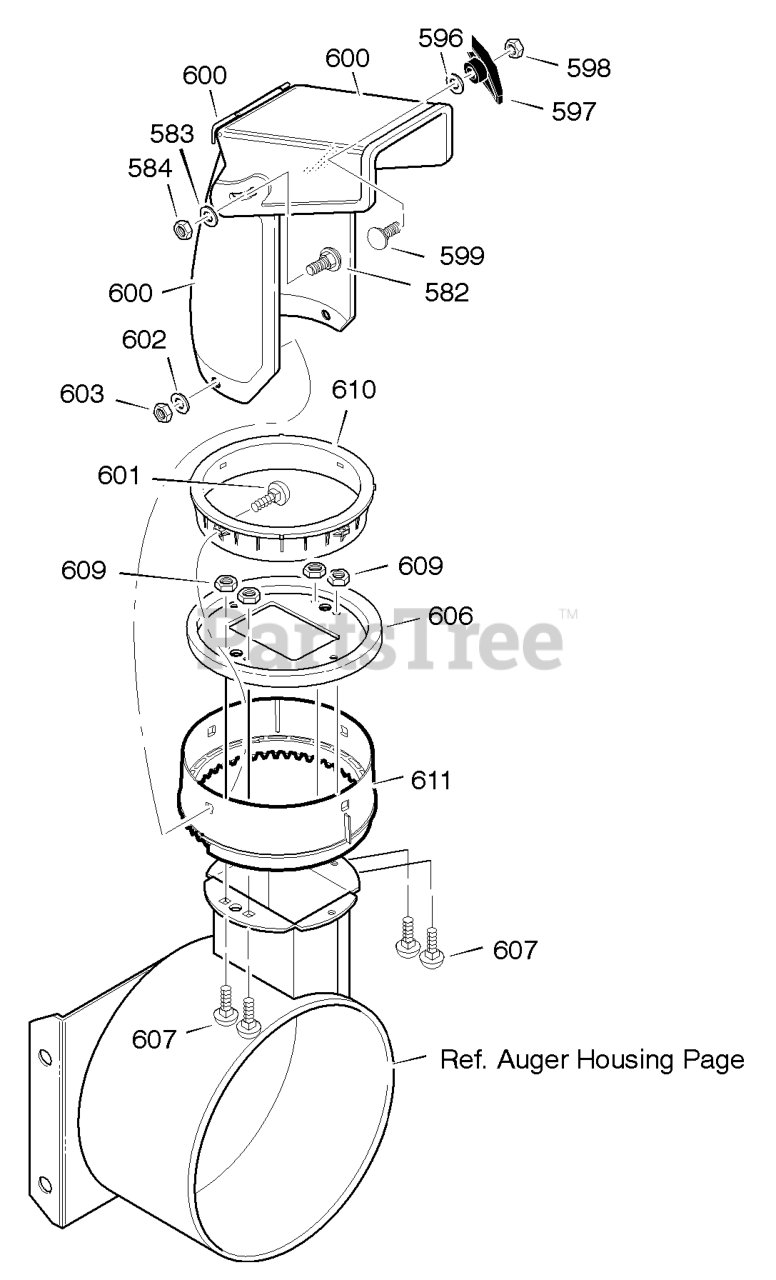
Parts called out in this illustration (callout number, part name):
582	BOLT, 5/16-18 X1.00
583	WASHER, FLAT
584	NUT, 5/16-18
596	WASHER
597	KNOB, T 3.00
598	NUT, 5/16-18 REGHEX
599	BOLT, 5/16-18 X1.50
600	CHUTE ASSEMBLY
601	BOLT, 5/16-18X1.00
602	WASHER, FLAT
603	NUT, 5/16-18 HEXNYL
606	CHUTE COLLAR
607	SCREW, 1/4-20 X 0.75
609	NUT, 1/4-20 HEX NYLOCK
610	RETAINER RING INNER
611	RETAINER RING OUTER
